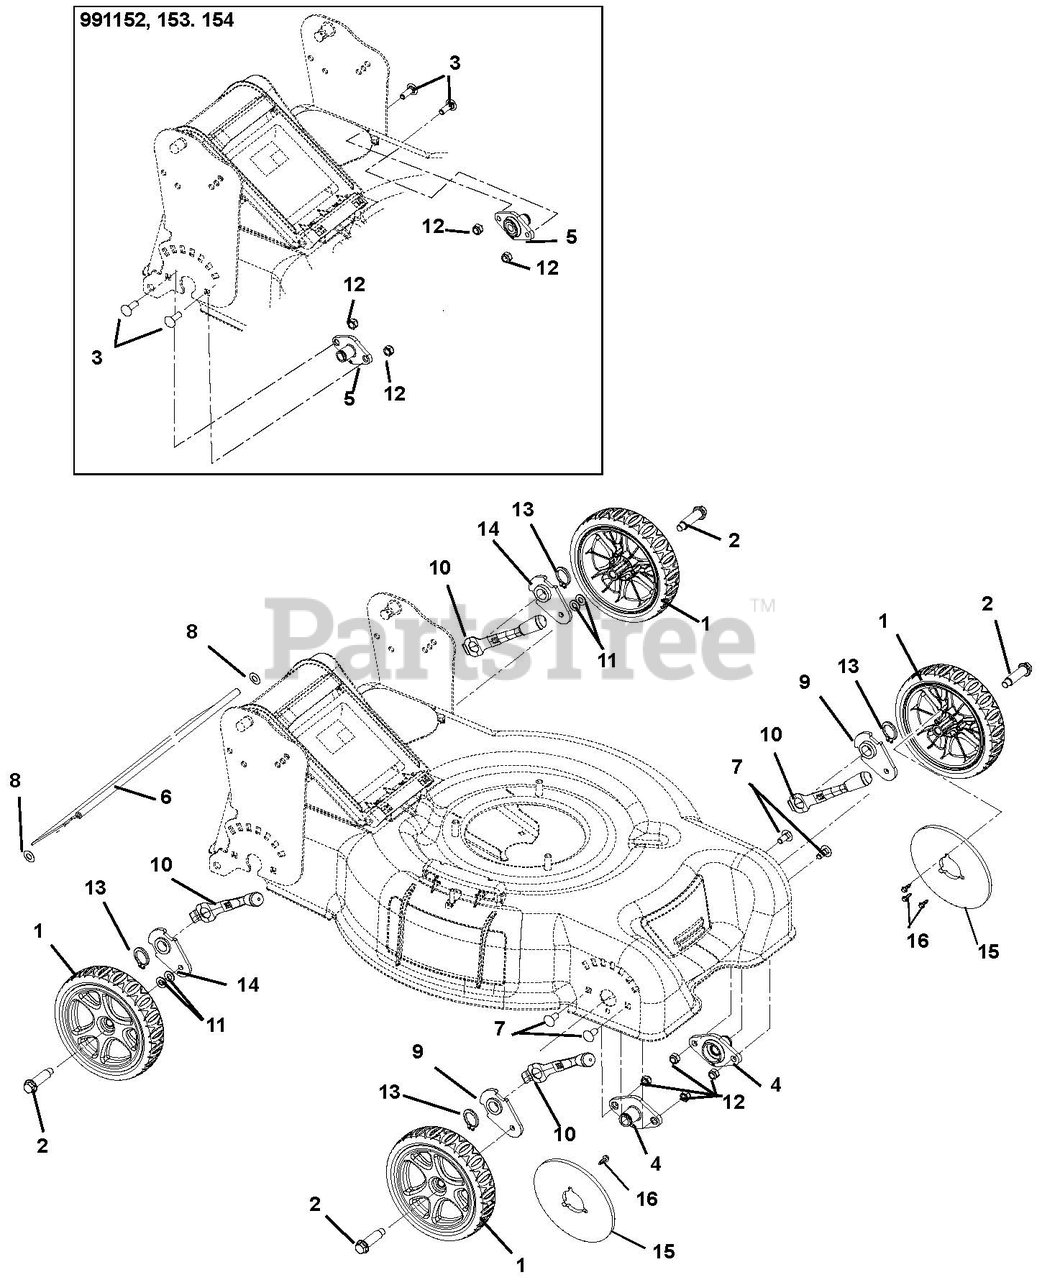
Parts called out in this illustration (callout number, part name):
1	WHEEL-8.5" WBLM ASSY
2	BOLT, WHEEL SHOULDER
3	@BLT-RDHDSQNK .31-18X1.00 G5YZ
4	WHEEL MOUNT HUB
5	KIT, WHEEL MOUNT HUB SERVICE
6	GUARD, WBLM
7	@BLT-RHDSSQNK .31-18X.75 G5YZ
8	RETAINER, .38 PUSH-ON
9	PLATE, FRONT WHEEL MOUNT
10	HANDLE, HOC
11	WSHR-HDND .406X.812X.055
12	@NUT-LK-TOP-FLG .31-18 YWZC
13	RG-RTNG-EXT .689X.078
14	PLATE, REAR WHEEL MOUNT
15	WEIGHT,WHEEL
16	SCR-TAP .25-15X.75 HI-LO
